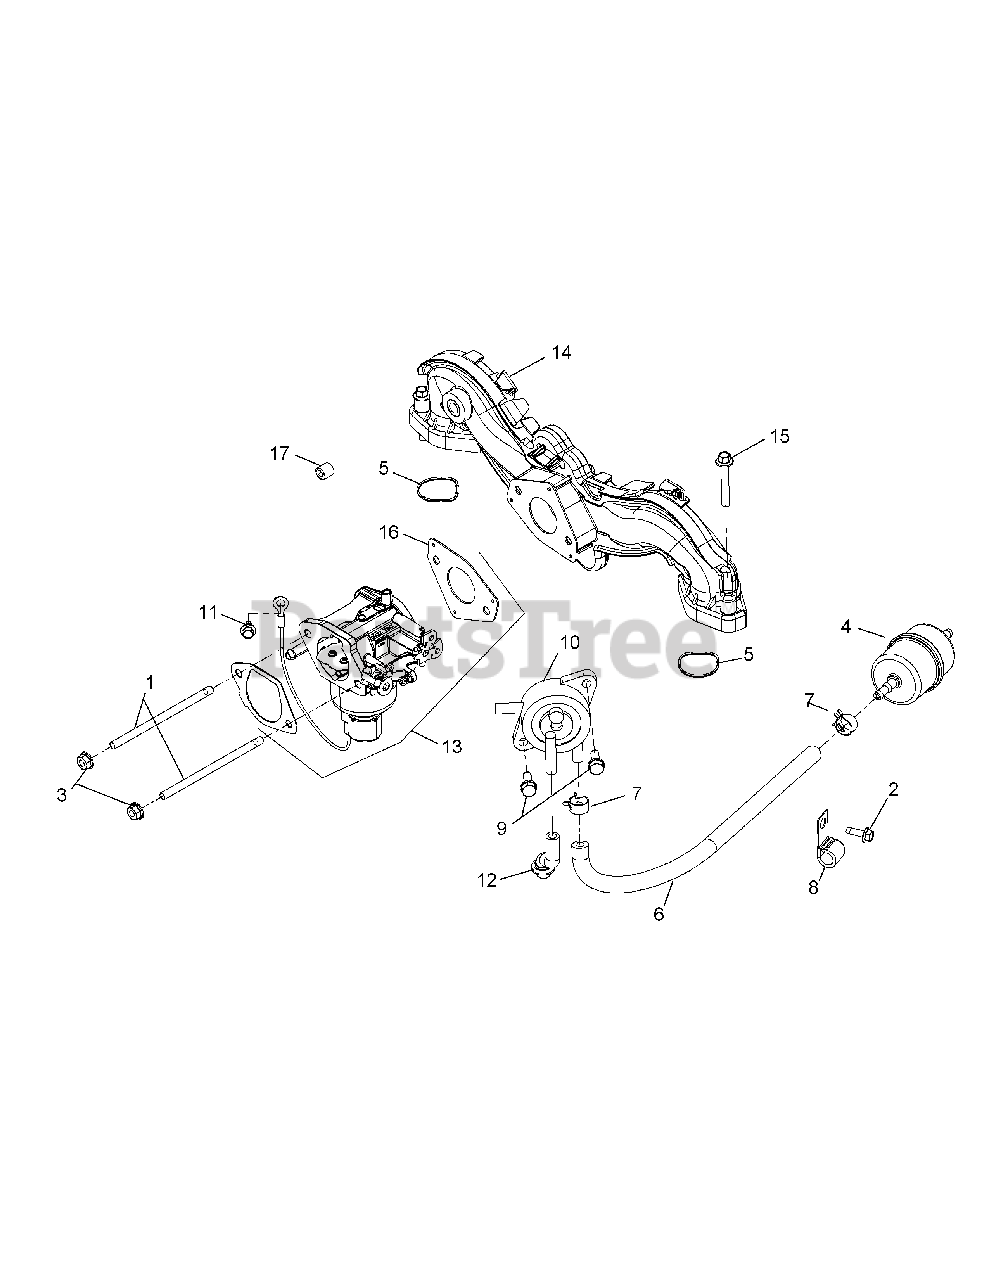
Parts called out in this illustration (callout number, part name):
2	Thread Forming Screw
3	Flange Nut, M6 x 1.0
4	Fuel Filter
5	Intake Port O-Ring
6	Fuel Line, 24"
7	Spring Hose Clamp
9	Tap Screw, M6 x 1.7 x 18
11	Thread Forming Screw
12	Pulse Pump Hose
13	Carburator Kit
14	Intake Manifold Kit
15	Flange Screw, M6 x 1.0 x 40
16	Carburetor Gasket
17	Pipe Plug, 1/8
